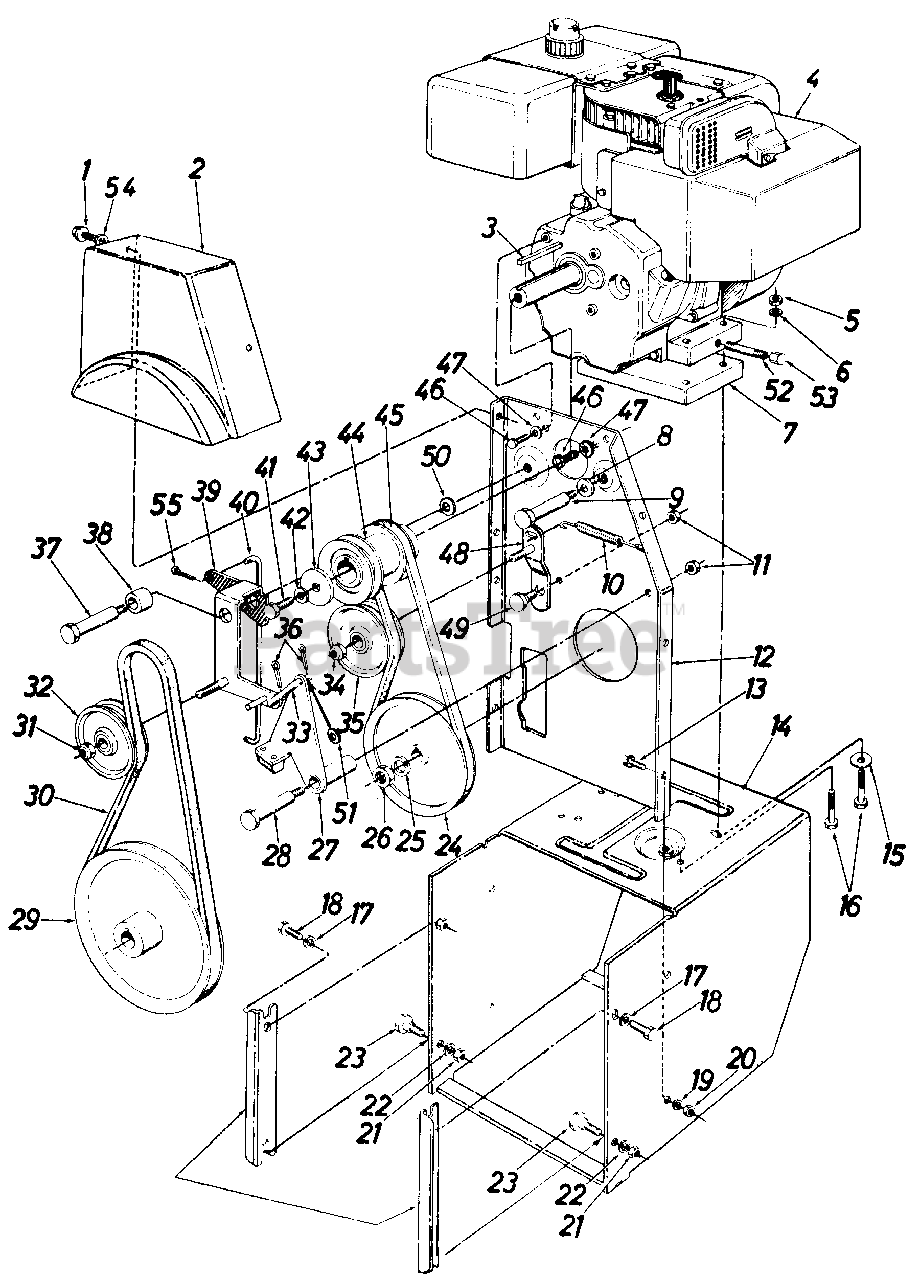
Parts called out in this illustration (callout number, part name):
1	Hex AB-Tap Scr. 5/16 x .75 Lg.
2	Belt Cover
3	Sq. Key 1/4" x 1.50" Lg.
4	Engine
5	Hex Nut 5/16-18 Thd.
6	L-Wash. 5/16"' I.D.*
7	Engine Spacer Ass'y.
8	Bell-Wash. .40 I.D. x .88 O.D.
9	Shld. Bolt .498" Dia. x 3.00"-Lg.
10	Ext Spring .38 O.D. x 3.18"
11	Hex Cent. L-Nut 3/8-16 Thd.
12	Engine Brkt. Ass'y.
13	Hex Sems Scr. 5/16-18 x .75" Lg.*
14	452 Frame Ass'y.
15	Fl-Wash. .345 I.D. x .75 O.D. x .060
16	Hex Bolt 5/16-18 x 2.50" Lg.*
17	L-Wash. 3/8" I.D. H.D.
18	Pilot Scr. 3/8-16 x .88" Lg.
19	L-Wash. 5/16" I.D.
20	Hex Nut 5/16-18 Thd.
21	Hex Nut 3/8-16 Thd.*
22	L-Wash. 3/8" I.D. H.D.
23	Shld. Bolt .498" Dia. x .340"-Lg.
24	V-Pulley .628 I.D. x 7.50 O.D.
25	L-Wash. for 5/8" I.D.*
26	Hex Ins. Jam L-Nut 5/8-18 Thd.
27	Brake Brkt. Ass'y.
28	Shld. Bolt .498" Dia. x 2.00" Lg.
29	V-Pulley .875 I.D. x 10.12 O.D.
30	V-Belt
31	Hex Ins. Jam L-Nut 3/8-24 Thd.
32	Fl-Idler w/Flanges 3.0 O.D.
33	Brake Linkage Ass'y.
34	Hex Ins. Jam L-Nut 3/8-24 Thd.
35	3.0" O.D. Fl-Idler w/Flanges
36	Int. Cot. Pin 3/32" Dia.
37	Shld. Bolt .625" Dia. x 2.750" Lg.
38	Spacer .75 O.D. x 1.00" Lg.
41	Hex Bolt 3/8-24 x 1.25" Lg.
42	L-Wash. 3/8" I.D. H.D.
43	Fl-Wash.
44	Engine Pulley-Double Groove
45	V-Belt
46	Hex Bolt 5/16-24 x .62" Lg.
47	Bell-Wash. .345 I.D. x .88 O.D. x .060
48	Drive Idler Brkt. Ass'y.
49	Shld. Bolt-.625" Dia. x .170" Lg.
50	Bell-Wash. .40 I.D. x 1.12 O.D.
51	Fl-Wash. .385" I.D. x .620" O.D.
52	Pipe Nipple-1/4" Pipe Thd. x 3.5" Lg.
53	Hex Hd. Cap 1/4-18 Pipe Thd.
54	Fl-Wash. .340 I.D. x .62 O.D. x .62
55	Int. Cot. Pin 5/16" Dia.
